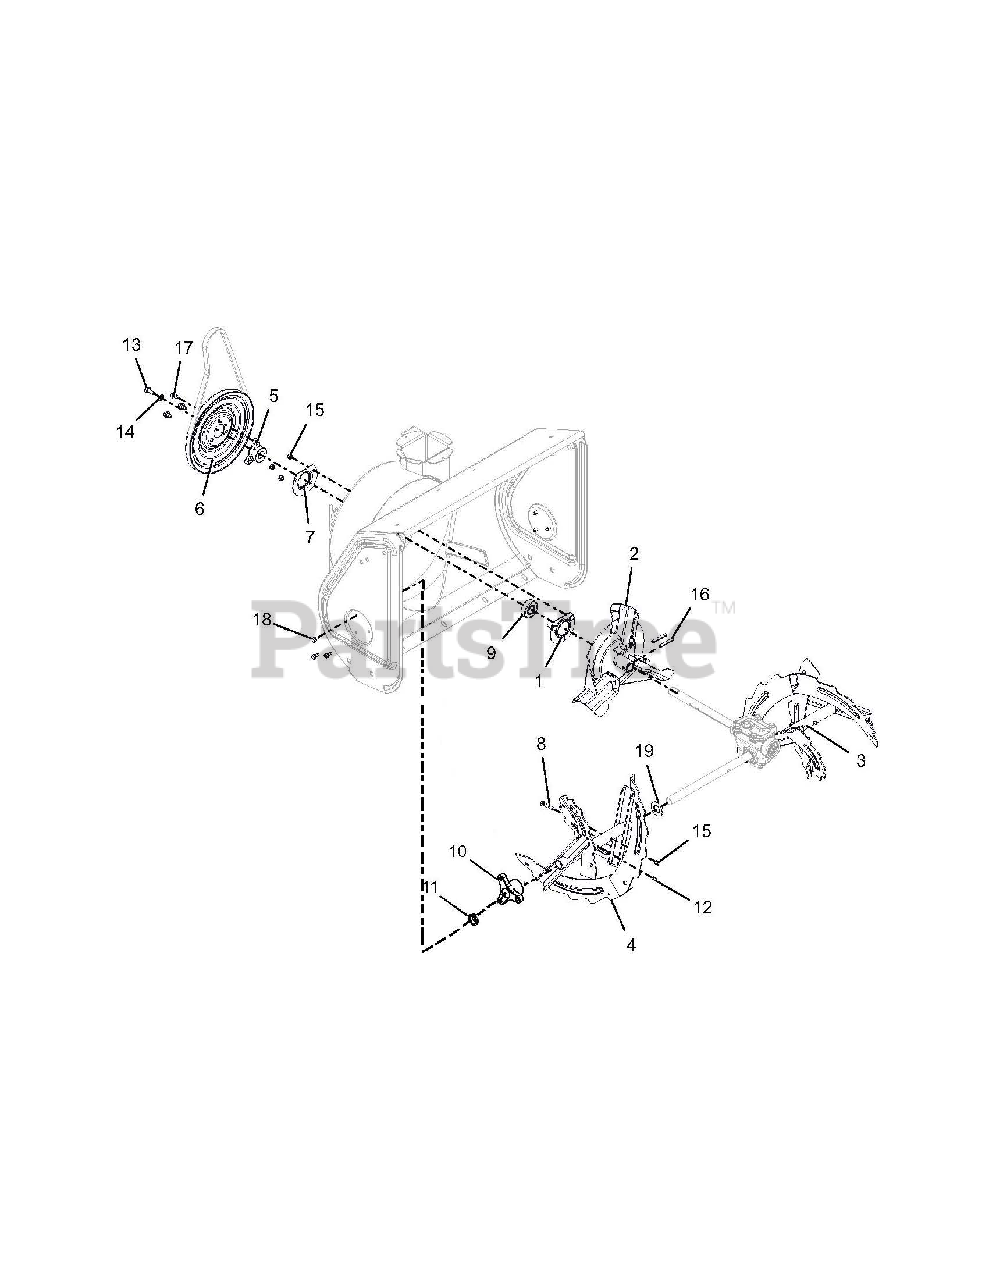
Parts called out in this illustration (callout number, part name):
1	BEARING FLANGE
2	IMPELLER, COMPACT 12" 3-BLADE
3	RAKE, 24" LH, BLK SERR W/ZERK
4	RAKE, 24" RH, BLK SERR W/ZERK
5	PULLEY HUB, BOLT-ON D-BORE .75
6	PULLEY,SPIN FORM SINGLE GROOVE
7	BEARING FLANGE
8	SHEAR BOLT
9	BRG-BALL .750X1.750X.50
10	BUSHING, RAKE SHAFT .75"
11	BSHG-FLG SPLIT NYLINER .75"ID
12	ZERK,FITTING .25X.125 DRIVE IN
13	BLT-HEX .31-24X.75 YWZC GR5
14	WSHR-LK .312X.097 HVY YWZC
15	@NUT-LK-CTR .25-20 YWZC
16	PIN-ROLL .250X1.75
17	@SCR-TAP .31-18X.50 HWH TR YWZ
18	SCR-TAP .25-20X.50 HWH TR YWZ
19	@WSHR-FL-STL.812X1.50X.135YWZC
